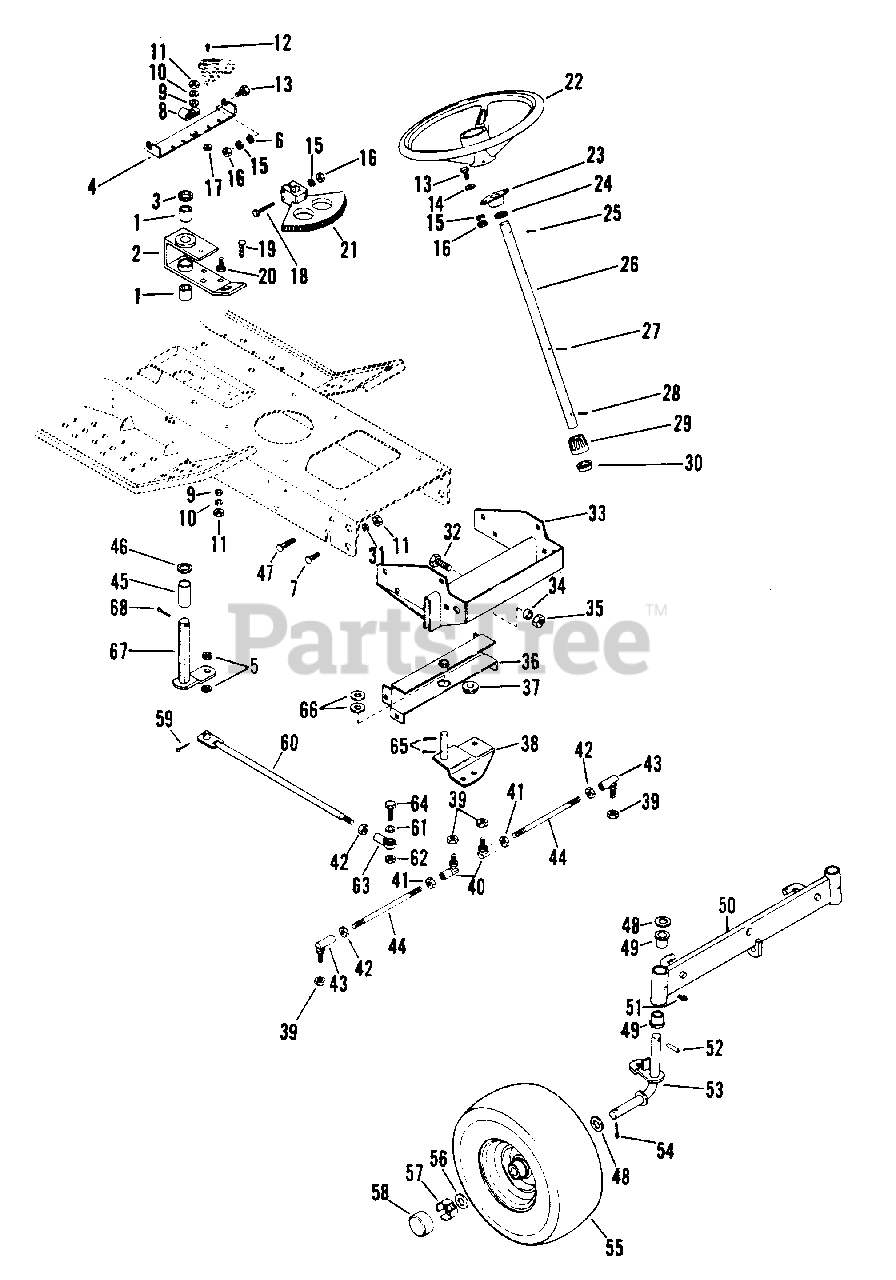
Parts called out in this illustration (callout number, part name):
1	BUSHING, SLEEVE
2	BRACKET, STEERING
3	WASHER
4	BRACE
5	WASHER, FLAT .531X1.000X.063
6	WASHER, FLAT .312X.734X.065
7	BOLT, CARRIAGE 3/8-16X.75
8	CLIP
9	WASHER, FLAT .406X.812X.065
10	WASHER, LOCK 3/8 REG.
11	NUT, HEX 3/8-16
12	SCREW, MACHINE 10-24X.625 PHD
13	BOLT, HEX 5/16-18X.75
14	WASHER, FLAT .312X.734X.065
15	WASHER, LOCK 5/16 SP
16	NUT, HEX 5/16-18
17	NUT, KEPS 10-24
18	BOLT, HEX 5/16-18X1.75
19	BOLT, 3/8-16X1.25 RD HD SQ NK
20	BOLT, HEX 3/8-16X1.00
21	GEAR, STEERING BEVEL
22	WHEEL, STEERING
23	BEARING, FLANGE
24	WASHER, FLAT .813X1.37X.100
25	PIN, SPRING .250X1.750
26	COLUMN, STEERING
27	PIN, SPRING .187X1.250
28	ROLLER, NEEDLE
29	GEAR, STEERING PINION
30	BUSHING, FLANGE
31	WASHER, LOCK 3/8 REG.
32	BOLT, HEX 1/2-13X1.25
33	SUPPORT, FRONT AXLE
34	SPACER
35	NUT, LOCK 1/2-13
36	CHANNEL, STEERING PIVOT
37	BUSHING, FLANGE
38	PIVOT, STEERING
39	NUT, LOCK 3/8-24
40	JOINT, BALL L.H.
41	NUT, HEX 3/8-24 L.H. THREAD
42	NUT, HEX 3/8-24
43	JOINT, BALL, R.H.
44	ROD, TIE
45	SPACER
46	WASHER, FLAT .938X1.750X.134
47	BOLT, 3/8-16X1.00 RD HD SQ NK
48	WASHER, FLAT .813X1.37X.100
49	BUSHING, FLANGE
50	WELDMENT, FRONT AXLE
51	FITTING, LUBE 1/4-28
52	PIN, SPRING
53	SPINDLE, R.H.
53	SPINDLE, L.H.
54	PIN, COTTER THD 1/4
55	ASSEMBLY, TIRE AND WHEEL
56	WASHER, FLAT .813X1.37X.100
57	GEAR, SPUR 30T
58	CAP, HUB
59	PIN, COTTER .125X1.00
60	LINK, DRAG
61	WASHER, FLAT .38X.75X.125
62	NUT, LOCK 3/8-16
63	END, ROD
64	BOLT, HEX 3/8-16X1.25
65	PIN, COTTER .125X1.25
66	WASHER, FLAT .656X1.312X.095
67	ARM AND SHAFT
68	PIN, COTTER .187X1.25
